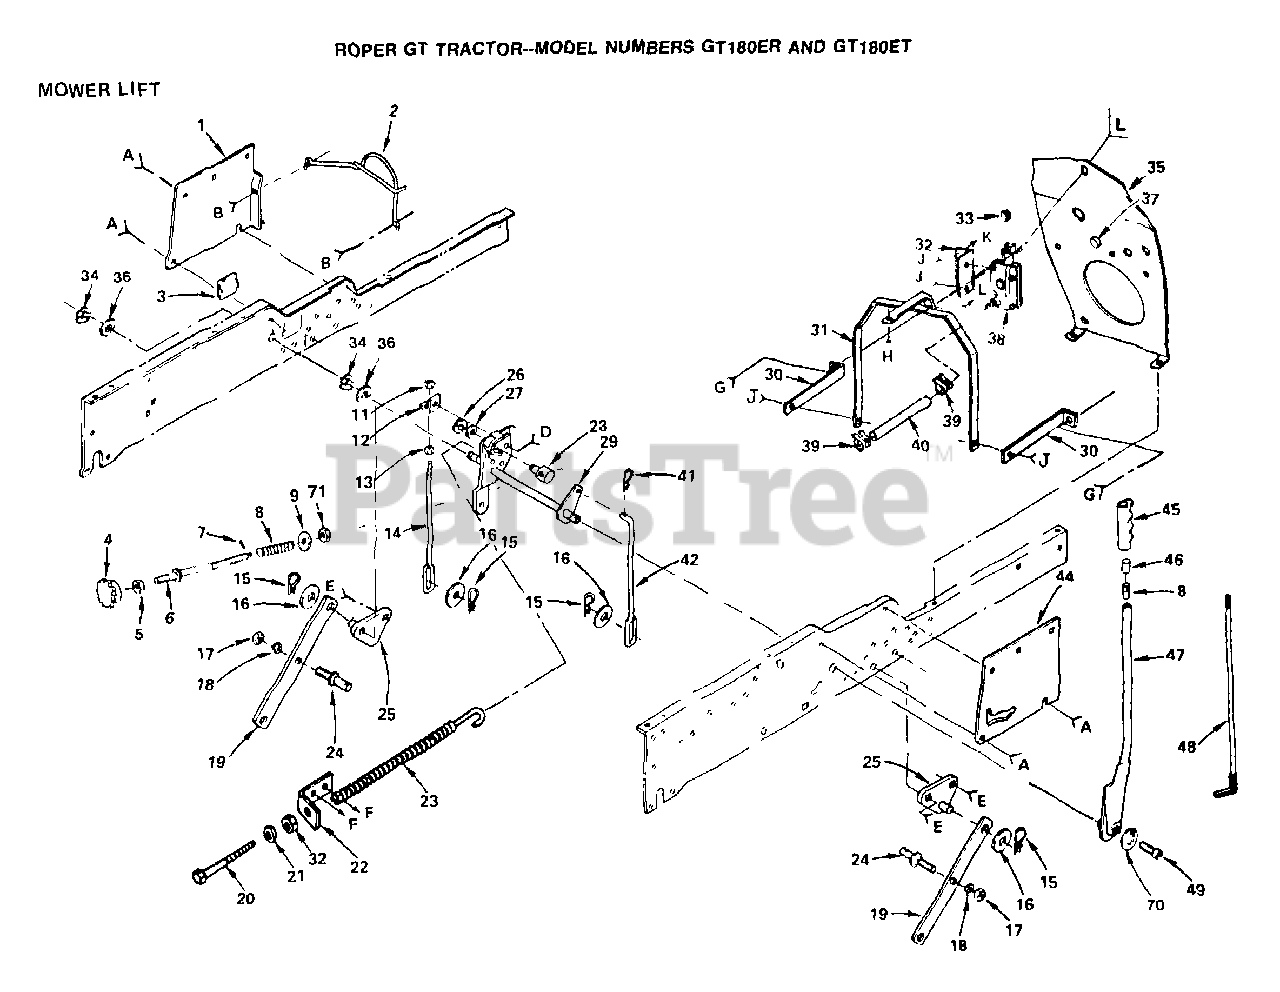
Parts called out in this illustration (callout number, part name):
5	NUT
6	ROD ADJ. T
8	SPRING T
9	WASHER
11	NUT
12	BRACKET T
13	NUT.HEX.3/8-16UNC
14	LINK-LIFT MOW T
15	SPRING H
17	NUT
18	LOCKWASHER
19	SUSPENSION ARM GT
20	BOLT-ADJ SPRING T
21	WASHER
24	PIVOT STUD GT
25	SUSP BRACKET T
26	KLIP RING
27	WASHER
28	TRUNION LT
30	BRKT-SHIELD, HEAT, SIDE
33	SNAP BUSHING T
34	E-RING
35	HEAT SHIELD T
36	WASHER
37	PLUG GT
42	LIFT LINK RH T
45	GRIP
48	LEVER ROD LT
49	"BOLT,HEX"
70	LOCKWASHER
71	NUT T
